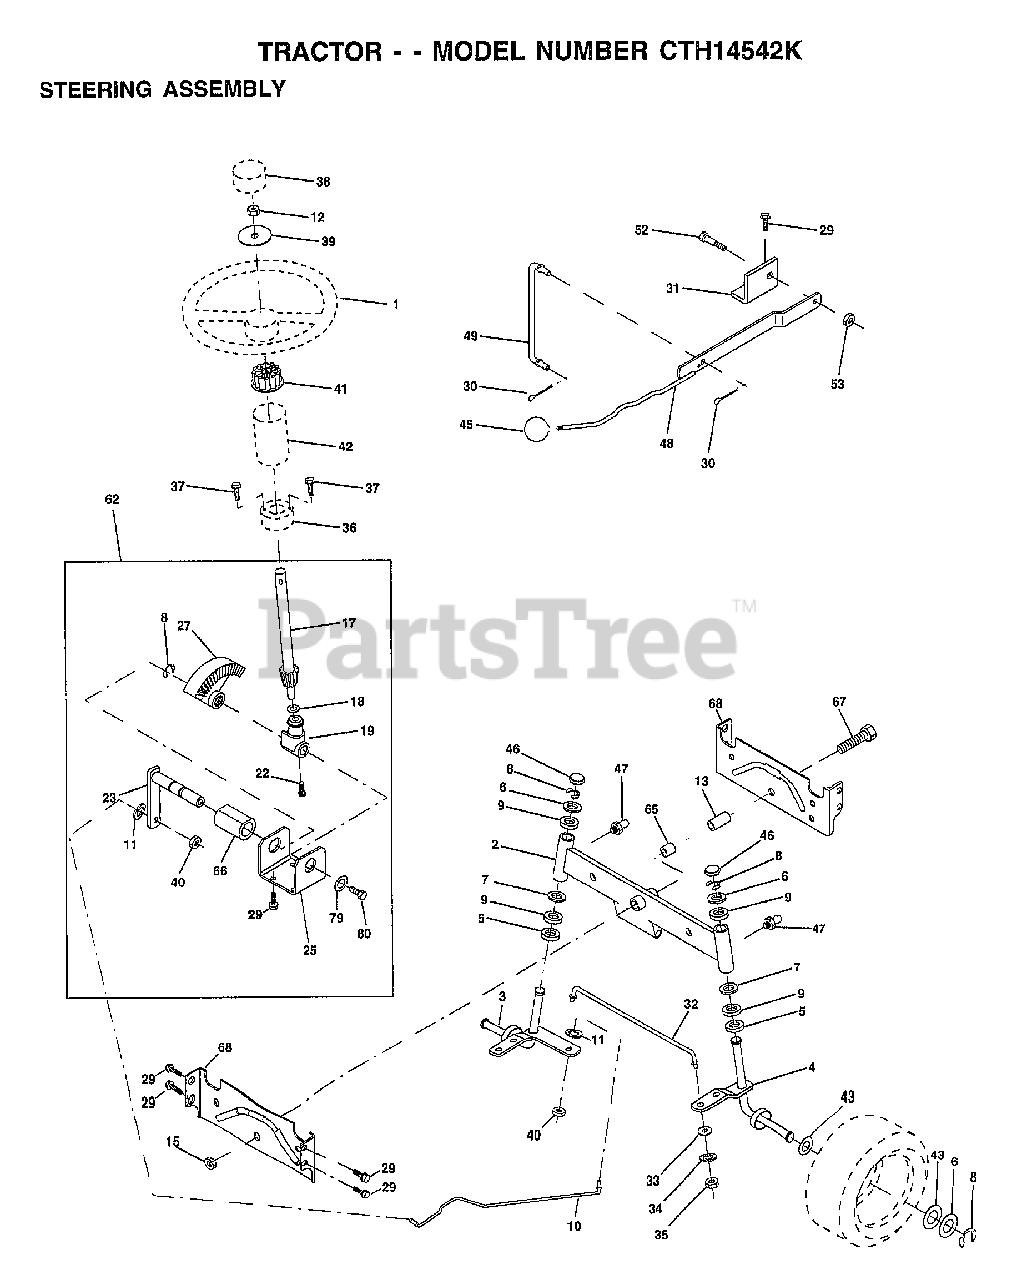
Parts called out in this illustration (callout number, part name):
1	WHEEL STR AYP BLK
2	AXLE ASM
3	SPINDLE.ASM.LH
4	"SPINDLE ASM,RH"
5	WASHER .T
6	WASHER
7	WASHER
8	RING
9	COL. SRTG. BEAR.
10	DRAGLINK-STAMPED
11	LOCKWASHER
13	BEARING AXLE
15	"NUT-LOC,FLANGE LT"
17	SHAFT ASM STEERNG
18	THRUST WASHER
19	SUPPORT.SHAFT.STEER
22	SCREW.HX.WSH.HD
23	SHAFT.ASM.PITMAN
25	BRKT-STEERING
27	GEAR SECTOR
29	SCREW
30	COTTER PIN
31	BRKT.PVT.MAN.LVR.
32	ROD.TIE.19.75
33	WASHER M
34	LOCKWASHER
35	NUT.LOCK.5/16-24
36	BUSHING.STRG.3/4
37	"SCREW-TT,10-32 FL"
38	CAP STEER AYP
39	WASHER
40	GRIPCO NUT
41	ADAPTER LT
42	BOOT SHAFT STEER
43	WASHER
45	KNOB T (1/2-HOLE)
46	CAP
47	ZERK M
48	LEVER.ASM.CLUTCH
49	LINK CLTCH W/NUTS
52	"BOLT, SHOULDER LT"
62	KIT.STEER.ASM.LT
65	SPACER AXLE
66	"BEARING-ARM,PITMA"
67	BOLT
68	BRACE AXLE
79	WASHER
80	BOLT.HX.NYLON3/8-16X3/
